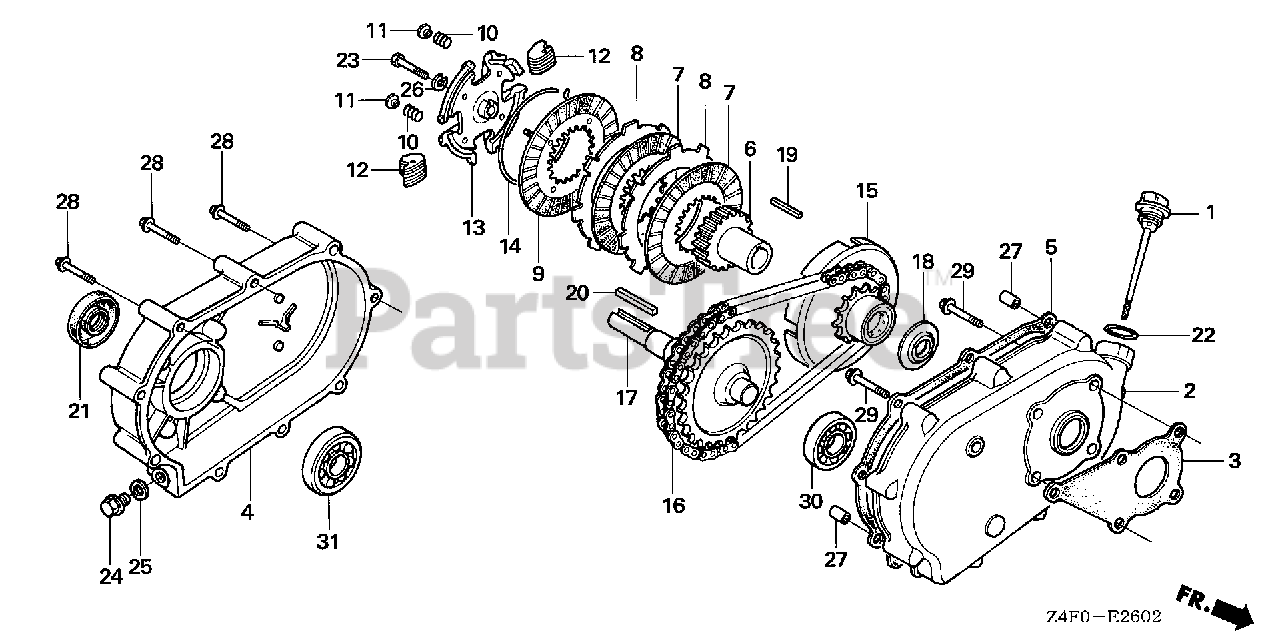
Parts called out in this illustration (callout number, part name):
1	CAP ASSY., OIL FILLER
2	CASE, REDUCTION
3	GASKET, REDUCTION CASE
4	COVER, REDUCTION
5	GASKET, REDUCTION COVER
6	CENTER, CLUTCH (28T)
7	DISK, CLUTCH FRICTION
8	PLATE, CLUTCH
9	PLATE, CLUTCH PRESSURE
10	SPRING, CLUTCH FREE
11	HOLDER, CLUTCH SPRING
12	WEIGHT, CLUTCH
13	HOLDER, CLUTCH WEIGHT
14	CENTER, CLUTCH WEIGHT
15	SPROCKET, DRIVE
16	CHAIN, DRIVE (RK428SH-36LE)
17	SHAFT, P.T.O. (28T)
18	WASHER, THRUST (18MM)
20	KEY (7X7X33) (OVER SIZE) (YELLOW)
21	OIL SEAL (30X50X7)
21	OIL SEAL (PJ30507)
22	O-RING (26X2.7)
23	BOLT, HEX. (8X35)
24	BOLT, DRAIN PLUG (12MM)
25	WASHER, DRAIN PLUG (12MM)
26	WASHER, SPRING (8MM)
27	PIN, DOWEL (8X10)
28	BOLT, FLANGE (6X55)
29	BOLT, FLANGE (8X22)
30	BEARING, RADIAL BALL (6205)
31	BEARING, RADIAL BALL (6206)
